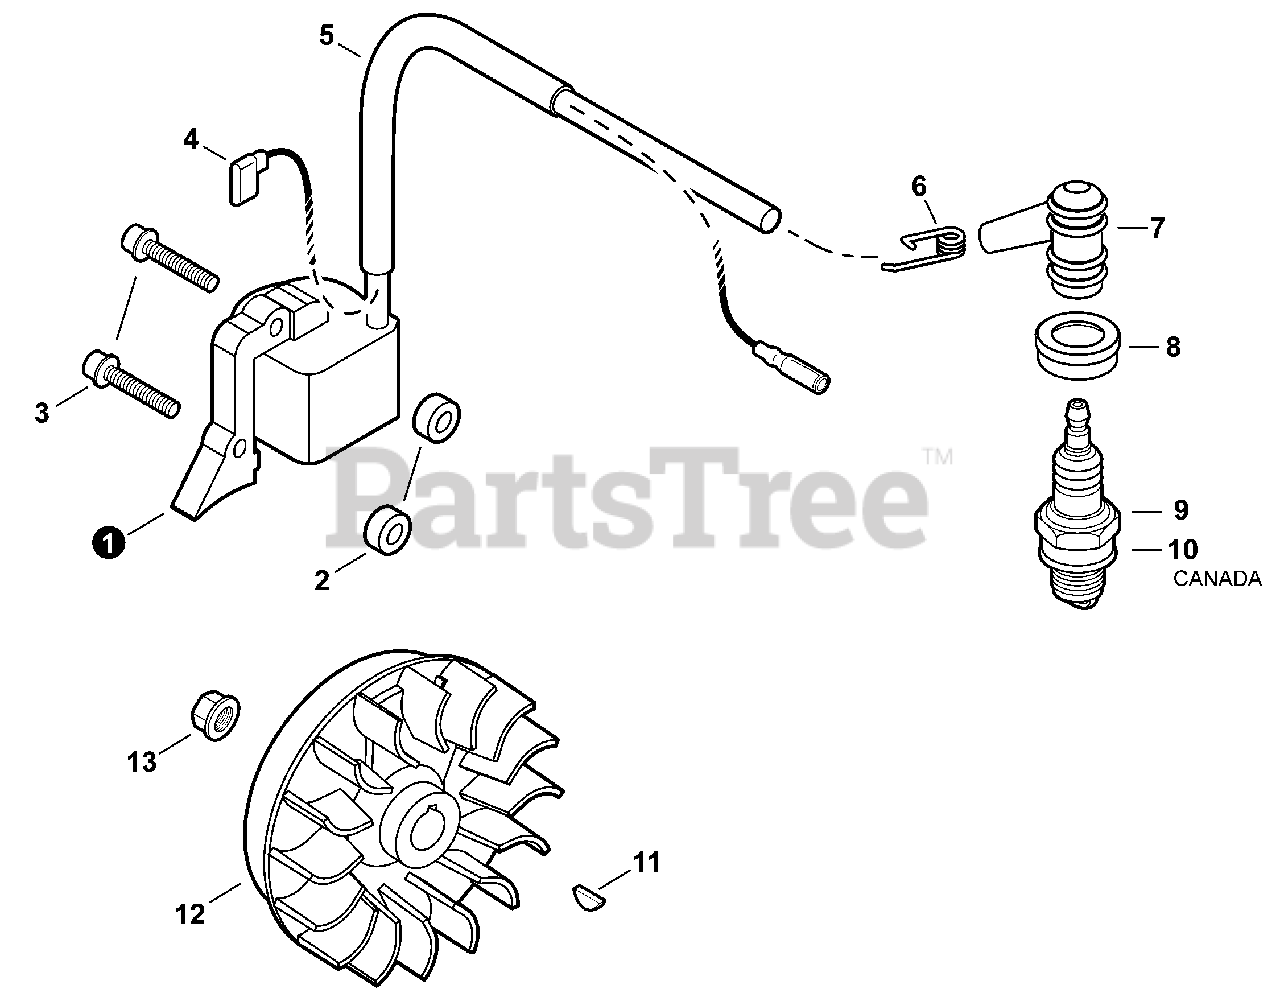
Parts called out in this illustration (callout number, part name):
1	COIL, IGNITION
2	INSULATOR 4.2×11×6
3	BOLT, ADHESIVE M4×24
4	LEAD, IGNITION L=180
5	SLEEVE, IGNITION COIL Ø8×L125
6	TERMINAL, SPARK PLUG
7	CAP, SPARK PLUG
8	SEAL, SPARK PLUG
9	SPARK PLUG - BPM-8Y
10	SPARK PLUG - BPMR-8Y
11	KEY, WOODRUFF 3×10
12	FLYWHEEL
13	NUT, CRANKSHAFT M8
